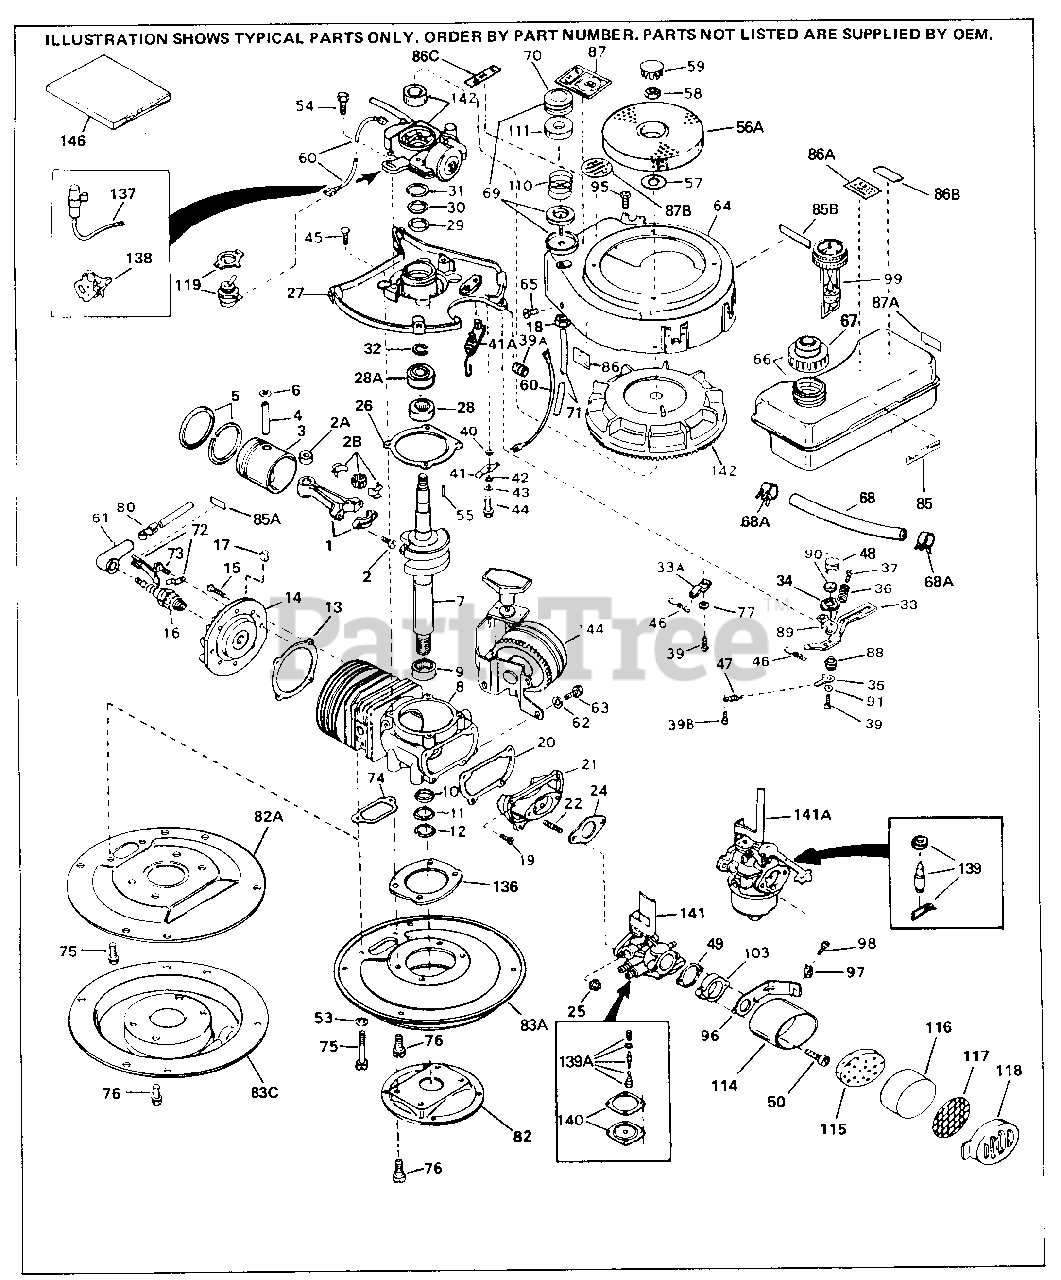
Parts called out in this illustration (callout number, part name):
1	"Rod Assy., Connecting Incl. 2, 2A, 2 B
2	Screw, Connecting rod
2A	Bearing, Cartridge
2B	Bearing & Liner Set, Needle 37 Needl es
3	Piston (Std.)
3	Piston (.010" OS)
4	Pin, Piston
5	Ring Set (Std.)
5	Ring Set (.010" OS)
6	Ring, Piston pin retaining
7	Crankshaft
8	Cylinder (Incl. 9 thru 12)
9	Bearing, Needle
10	Seal, Crankshaft
11	Retainer, Crankshaft seal
12	Ring, Crankshaft seal retainer
13	* Gasket, Cylinder head
14	Head, Cylinder
15	Screw, 1/4-20 x 3/4"
16	Resistor Spark Plug - RJ17LM
16	Resistor Spark Plug
19	Screw, 10-24 x 1/2"
20	* Gasket, Reed plate
21	Plate Assy., Reed (Incl. 22)
22	Stud, Carburetor
24	* Gasket, Carburetor
25	Nut, Whiz lock 1/4-28
26	* Gasket, Housing base
27	Base Assy., Housing Incl. 28, 29, 30 & 31
28	Bearing, Needle
29	Seal, Crankshaft
30	Retainer, Crankshaft seal
31	Spring, Crankshaft seal retainer
32	Ring, Retainer (Use as required)
33	Lever, Control
35	Lever, Adjusting
37	Screw, 5-40 x 7/16"
39	Screw, Torx T-25, 10-24 x 7/8
45	Screw, 1/4-20 x 5/8"
46	Spring, Governor
49	Gasket, Air cleaner
50	Screw, 10-32 x 5/8"
53	Washer (Use as required)
54	Screw, 1/4-20 x 3/4"
55	Key, Flywheel
57	Washer, Lock
58	Nut, Flywheel
60	Wire, Cut off
63	Pop Rivet (3/16" dia.) (Buy locally) As req.
63	Screw, 1/4-28 x 3/8" Use as required
64	Blower Housing On some late productio n models, the top mounted rewind star ter is riveted to the blower housing. If either the starter or blower hou sing needs replacement, the other may need the holes used for pop riveting enlarged to accomodate us
65	Screw, 1/4-20 x 3/8"
66	Fuel Tank (Incl. 67)
67	Fuel Cap (Standard)
68	Fuel Line (8.62")
68A	Fuel Line Clamp
74	* Gasket, Exhaust NOTE: Some engines m ay havebeen built with two #510257 ga sketsand one #510272 gasket. In that case, two longer mounting screws #65 0802 are required.
74	* Gasket, Exhaust
76	Screw, 5/16-18 x 5/8"
77	Washer, Flat #10
80	Terminal, Lead wire
86	Decal, Instruction
87	Decal, Name
96	Bracket, Boden wire
97	Conduit Clip
98	Screw, 10-32 x 3/8"
114	Body, Air filter
115	Air Filter
116	Air Filter
117	Air Filter
118	Cover, Air filter
119	Switch, Toggle
137	Condenser (also available in Packaged Part #740037B)
138	Breaker Points (also available in Pac kaged Part #740037B)
139A	Inlet Needle, Seat, Spring & Gasket A ssy.
140	Diaphragm & Gasket Assy.
141	Carburetor (Incl. 24, 139A & 140) (Re fer to Division 5, Section A, page 10 6 for breakdown)
142	Magneto NOTE: The complete magneto i s not available as an assembly. The magneto number is shown for reference purposes only. Order component part s individually, as shown in parts lis t. (Refer to Division 5, Section B, p age 28 for breakdown)
146	* Gasket Set (Incl. items marked *)
